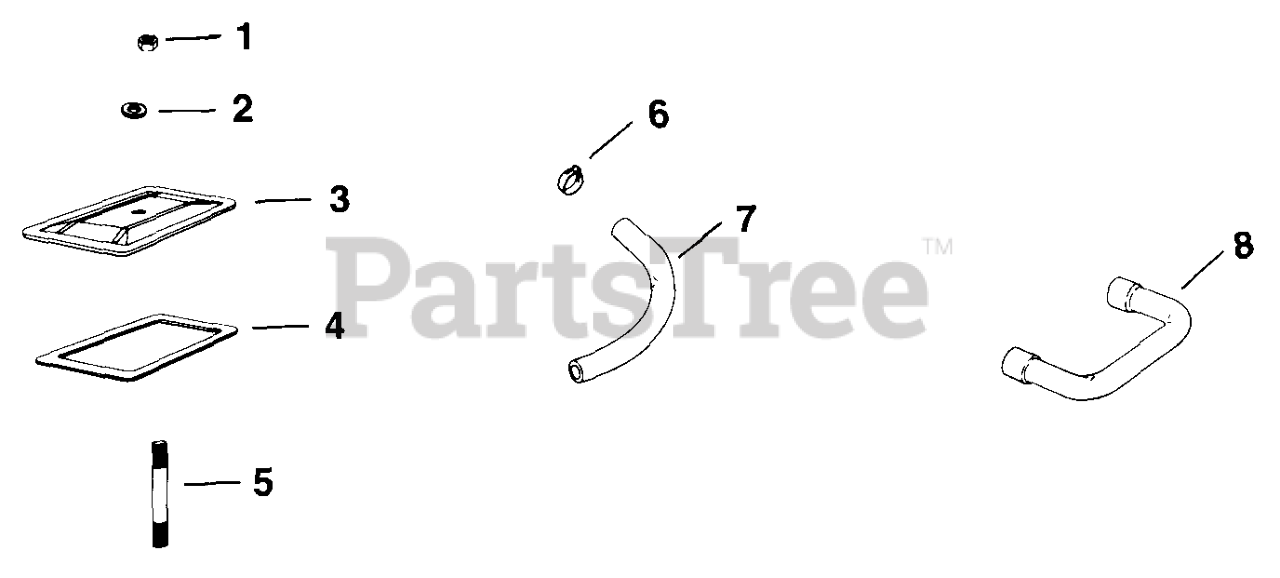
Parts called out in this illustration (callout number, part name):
1	NUT, 1/4-20 GRADE 2 USE 25 100 20-S
3	COVER, VALVE (#DSC)
4	GASKET - DISCONTINUED
5	STUD, 1/4-20x2-9/16" - DISC.
6	CLAMP, HOSE USE 25 237 12-S
8	HOSE-(#DSC)
